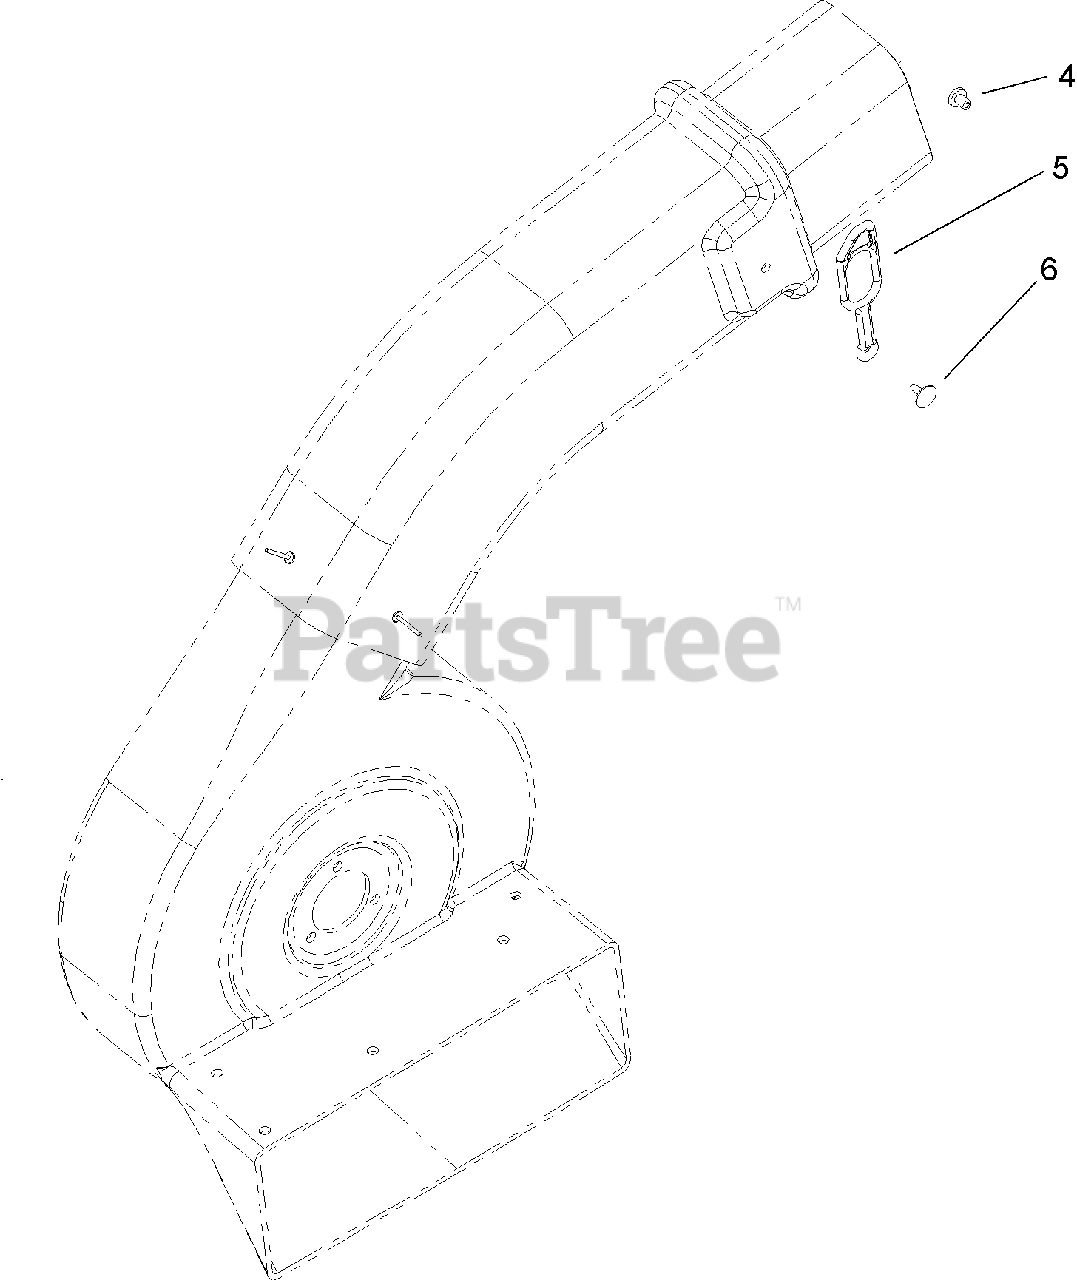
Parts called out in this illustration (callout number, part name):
4	SPACER-INTERLOCK
5	RETAINER-DUCT
6	FASTENER-PANEL
